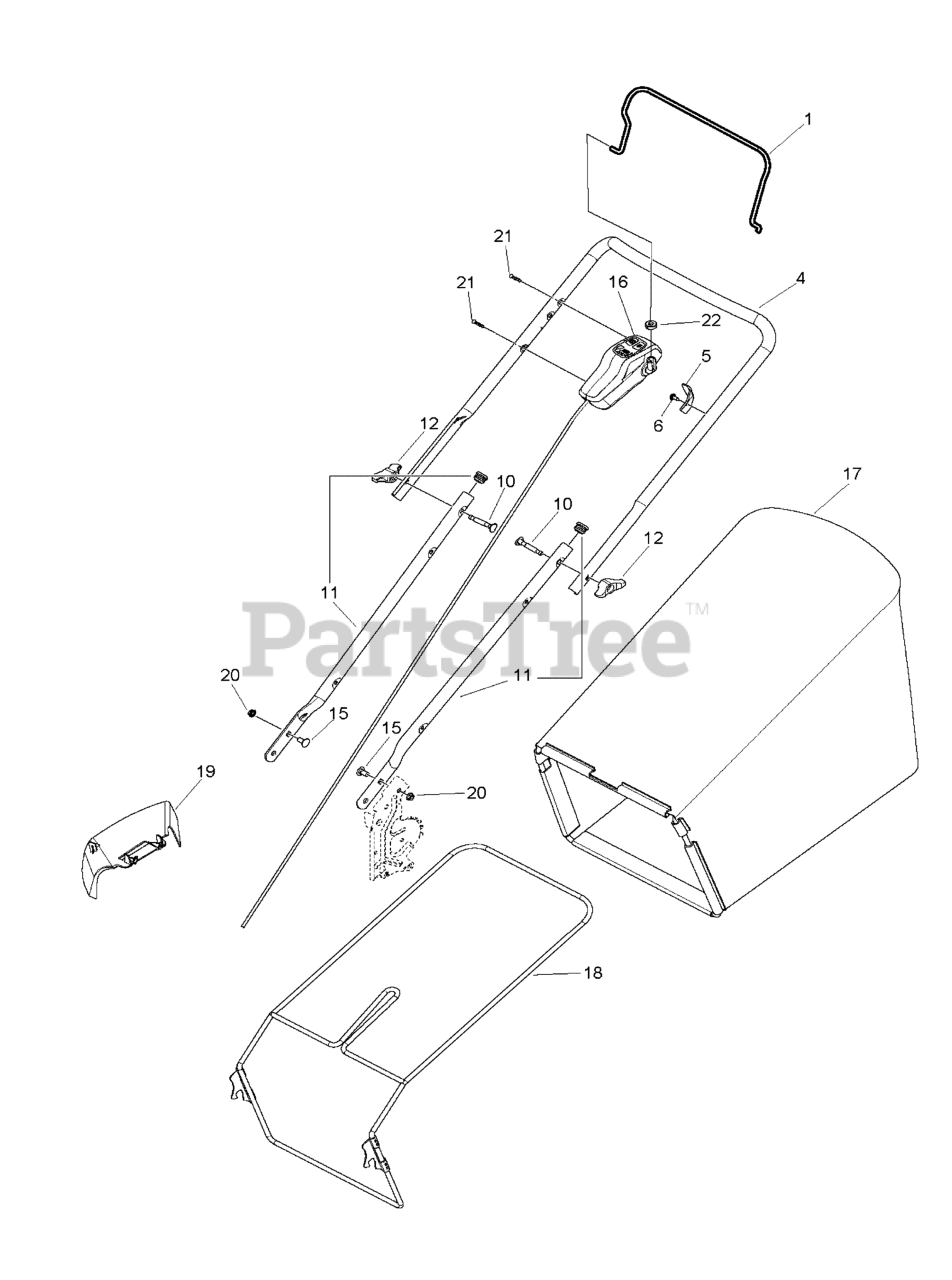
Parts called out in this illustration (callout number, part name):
1	Bail
4	HANDLE, Upper
5	UP-STOP, Left
6	SCREW, #10-16 x 5/8
10	Bolt
11	HANDLE, Lower
12	KNOB, Handle
15	BOLT, Carriage, 5/16-18 x 5/8
16	CONTROL
17	BAG, Grass
18	Frame, Grass Bag
19	DEFLECTOR
20	Nut, Hex
21	SCREW
22	RETAINER, Bail
